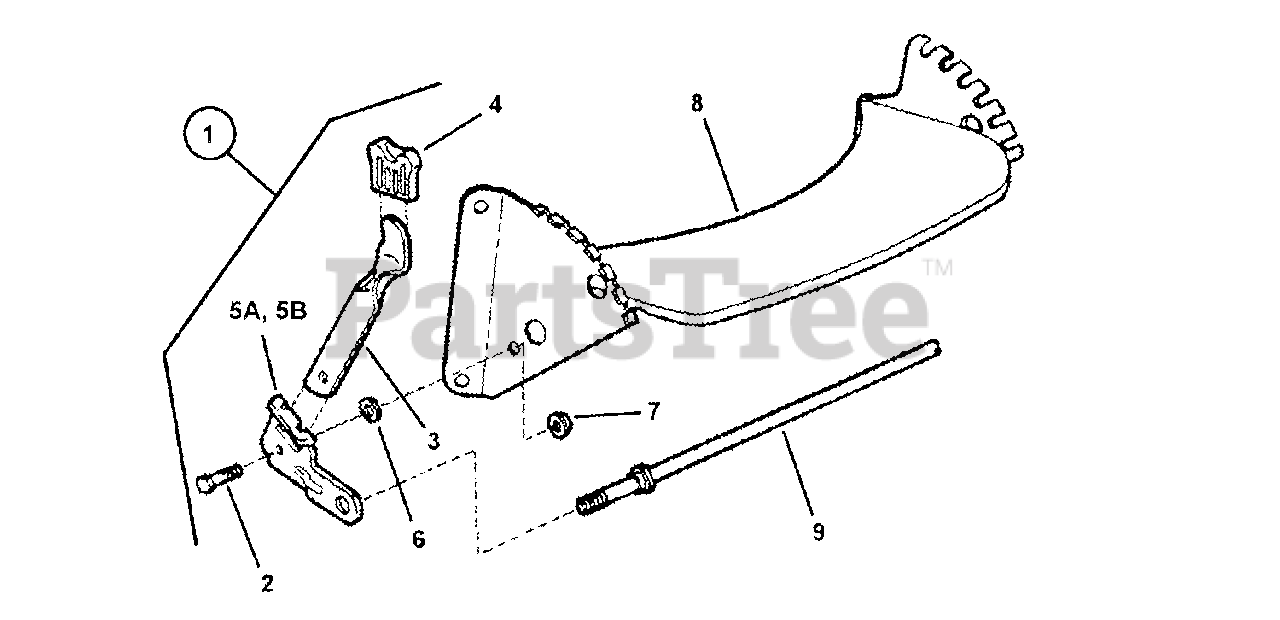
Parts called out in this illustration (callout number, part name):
1	ASSEMBLY, Right Wheel Arm
2	BOLT, 5/16-18 Hex washer Face Shoulder
3	LATCH, Height
4	GRIP, Height Latch
5A	WHEEL ARM, R.H. Front (Round Hole)
6	RETAINER, 5/16" Bolt
7	NUT, 5/16-18 Hex Flange Lock, GR 5
8	WELDMENT, Front Wheel Bracket
9	AXLE, 21"
